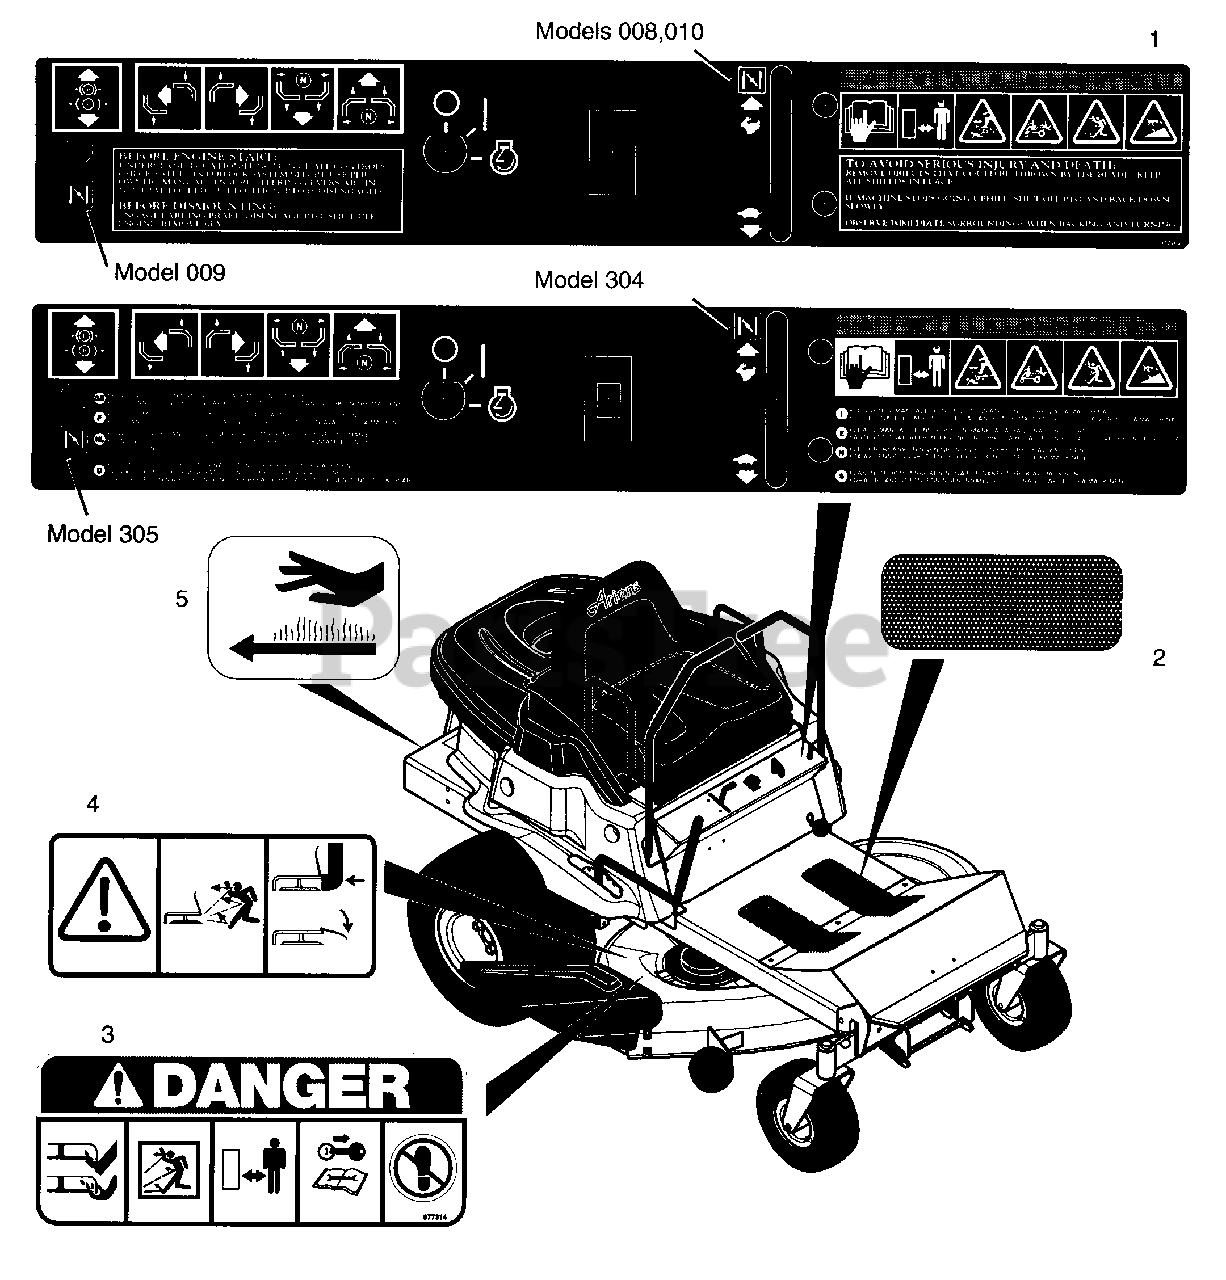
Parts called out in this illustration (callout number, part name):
1	DECAL EZR 1440/1540 CONTROL
2	NONSKID COVER
3	DECAL, MOWER PAN DANGER
4	DECAL- DISCHARGE
5	DECAL- HOT SURFACE SYMB.
